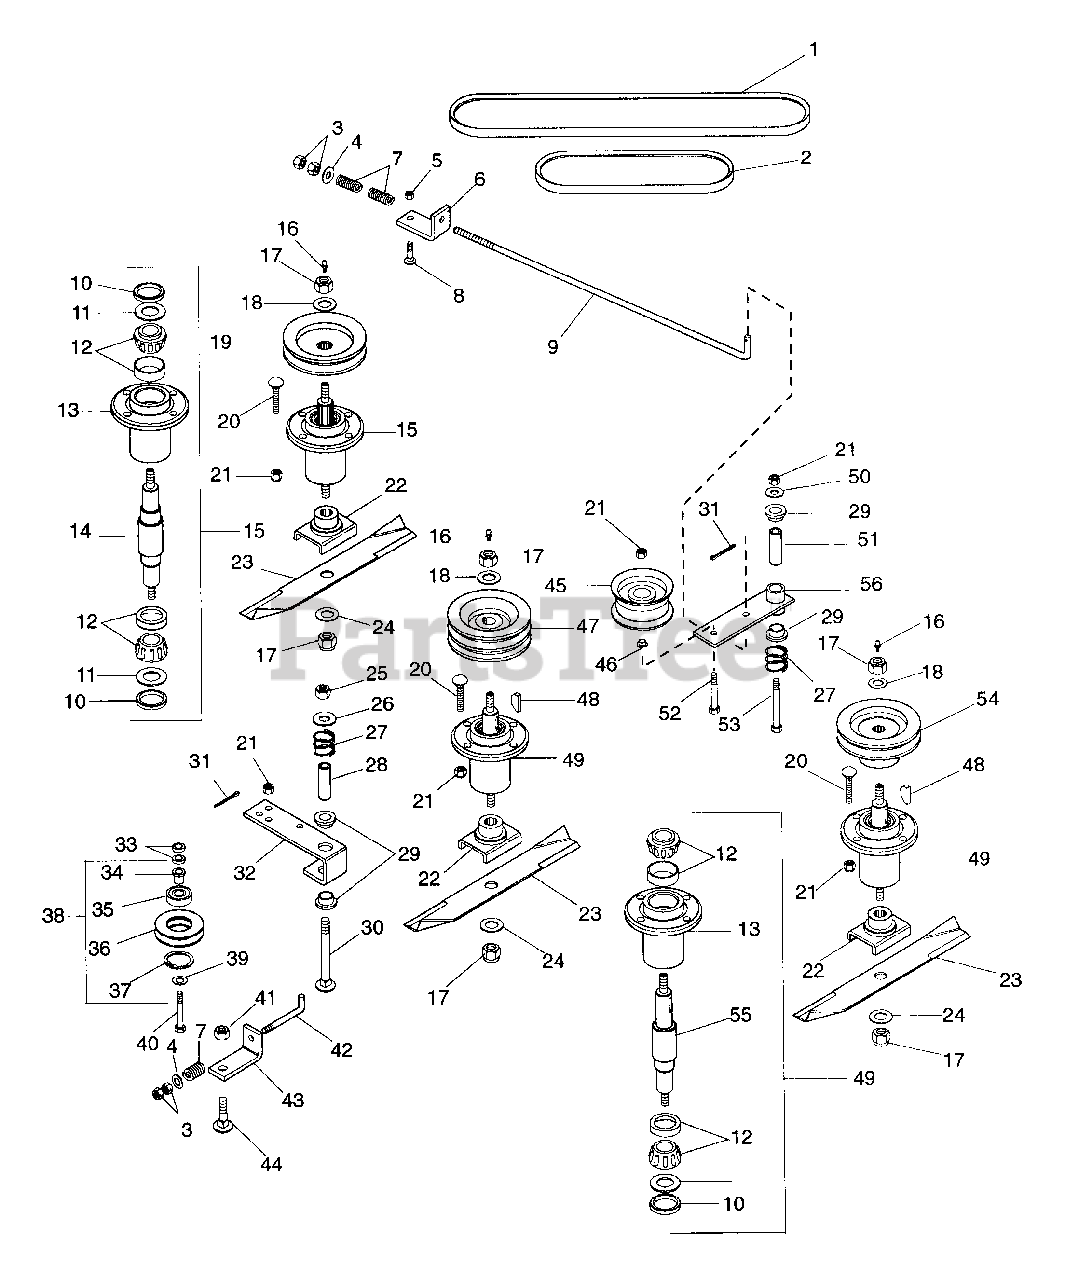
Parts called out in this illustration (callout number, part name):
1	V-belt A-RMA 54.90 x 17/32
2	V-belt A-RMA 18.05 x .495
3	Nut-Hex .375 - 16 Grade 2
4	Washer-Flat Steel .406 x .812 x .065
5	Nut-Locking-Nylon .312 - 18 Grade 2
6	Bracket, Belt Tensioner
7	Spring-Compression .125 x .78 x 1.00
8	Bolt, Round Head Square Neck .31 - 18 x 1.0
9	Rod, Idler L.H.
10	Steel Seal
11	Washer-Flat-Steel .97 x 1.865 x .03
12	Assembly, Bearing Cup & Cone
13	Housing, Bearing
14	Shaft, Spindle
15	Spindle, Assembly
16	Fitting, Lube 1/8
17	Nut-Locking-Nylon .625-11 Grade 2
18	Washer-Flat-Steel .687 x 1.312 x .135
19	Sheave, Spindle
20	Bolt-Round Head Square Neck .38 - 16 x 1.375
21	Nut-Locking-Nylon .375 - 16 Grade 2
22	Weldment, Blade Cradle
23	Blade, 50 Inch Mower
23	Blade, 50" Sand (Export)
24	Washer-Flat-Nylon .656 x 1.312 x .095
25	Nut-Locking .50-13
26	Washer-Flat-Steel .531 x 1.250 x .100
27	Spring-Compression .085 x 1.00
28	Bushing, Steel .560 x .750 x 2.44
29	Bushing-Flange .762 x 1.0 x .580 x 1.48
30	Bolt-Round Head Square Neck .50 - 16 x 3.50
31	Pin, Cotter .09 x .75
32	Arm, Idler Pivot
33	Bushing .406 x .750 x .188
34	Bushing-Flange .786 x 1.0 x .79
35	Bearing - Ball 1.85 x .787 x .55
36	Sheave, Idler
37	Ring-Retaining Internal 2.05 x .062
38	Assembly, Idler Sheave
39	Washer-Flat-Steel .375 x 1.125 x .065
40	Bolt-Hex .38 - 16 x 2.00 Grade 2
41	Nut-Locking-Nylon .50 - 13 Grade 2
42	Rod, Idler
43	Bracket, Belt Tensioner
44	Bolt-Round Head Square Neck .500 - 13 x 1.50
45	Idler-Flat 4 - .687 x .38
46	Bushing-Flange .406 x .88 x .270 x .140
47	Sheave, Spindle
48	Key, Woodruff .25 x 1
49	Assembly, Spindle
50	Washer-Flat-Steel .438 x 1.0 x .083
51	Bushing, Steel .437 x .750 x 2.44
52	Bolt-Hex .38 - 16 x 2.25 Grade 5
53	Bolt-Hex .38 - 16 x 3.25 Grade 5
54	Sheave, Spindle
55	Shaft, Spindle
56	Weldment, Idler Arm
